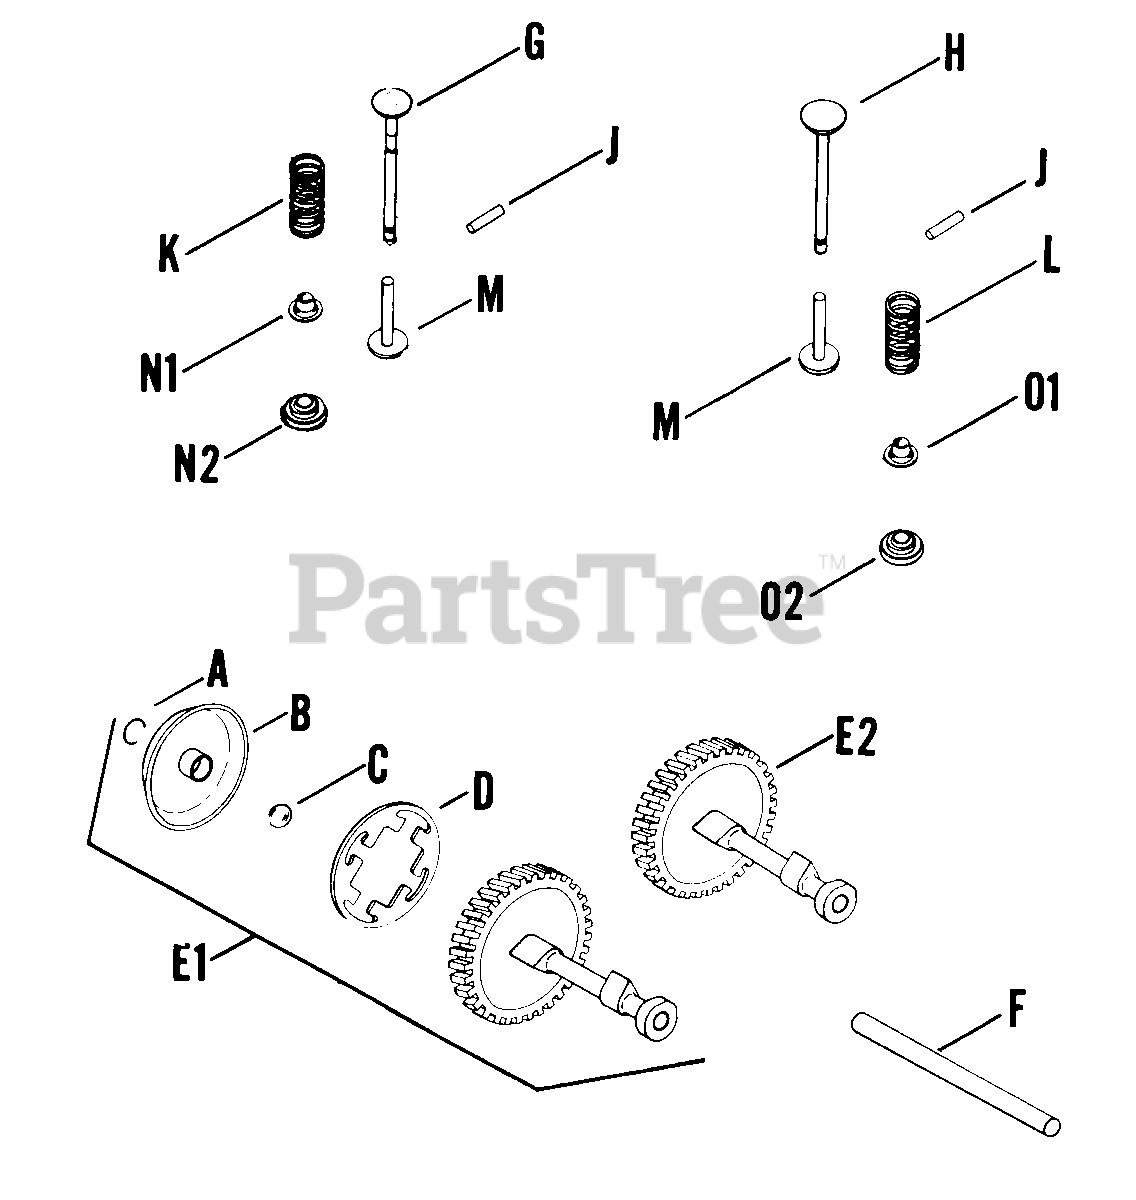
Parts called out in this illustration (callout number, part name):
A	RING - DISCONTINUED
E1	CAMSHAFT - DISCONTINUED
F	PIN - DISCONTINUED
G	VALVE-DISCONTINUED
H	VALVE - DISCONTINUED
J	PIN - (#DSC)
M	TAPPET - (#DSC)
N2	ROTATOR - (#DSC)
O2	ROTATOR - (#DSC)
